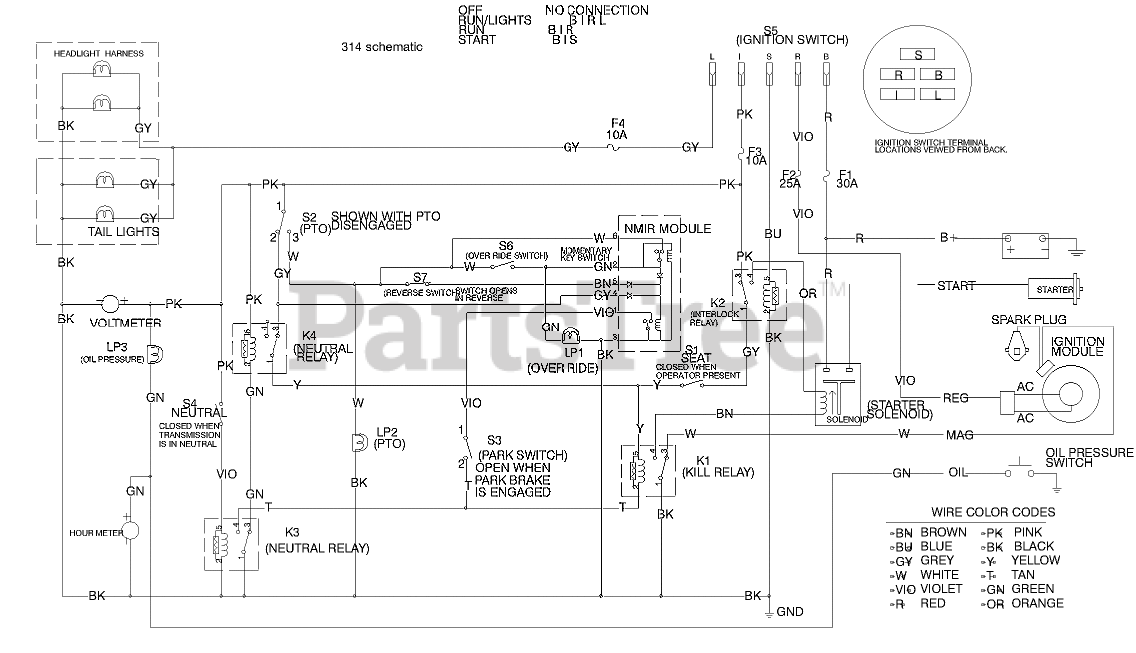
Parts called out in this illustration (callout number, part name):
F1	FUSE-30 AMP
F2	FUSE-BLADE, 25 AMP
F3	FUSE-10 AMP
F4	FUSE-10 AMP
